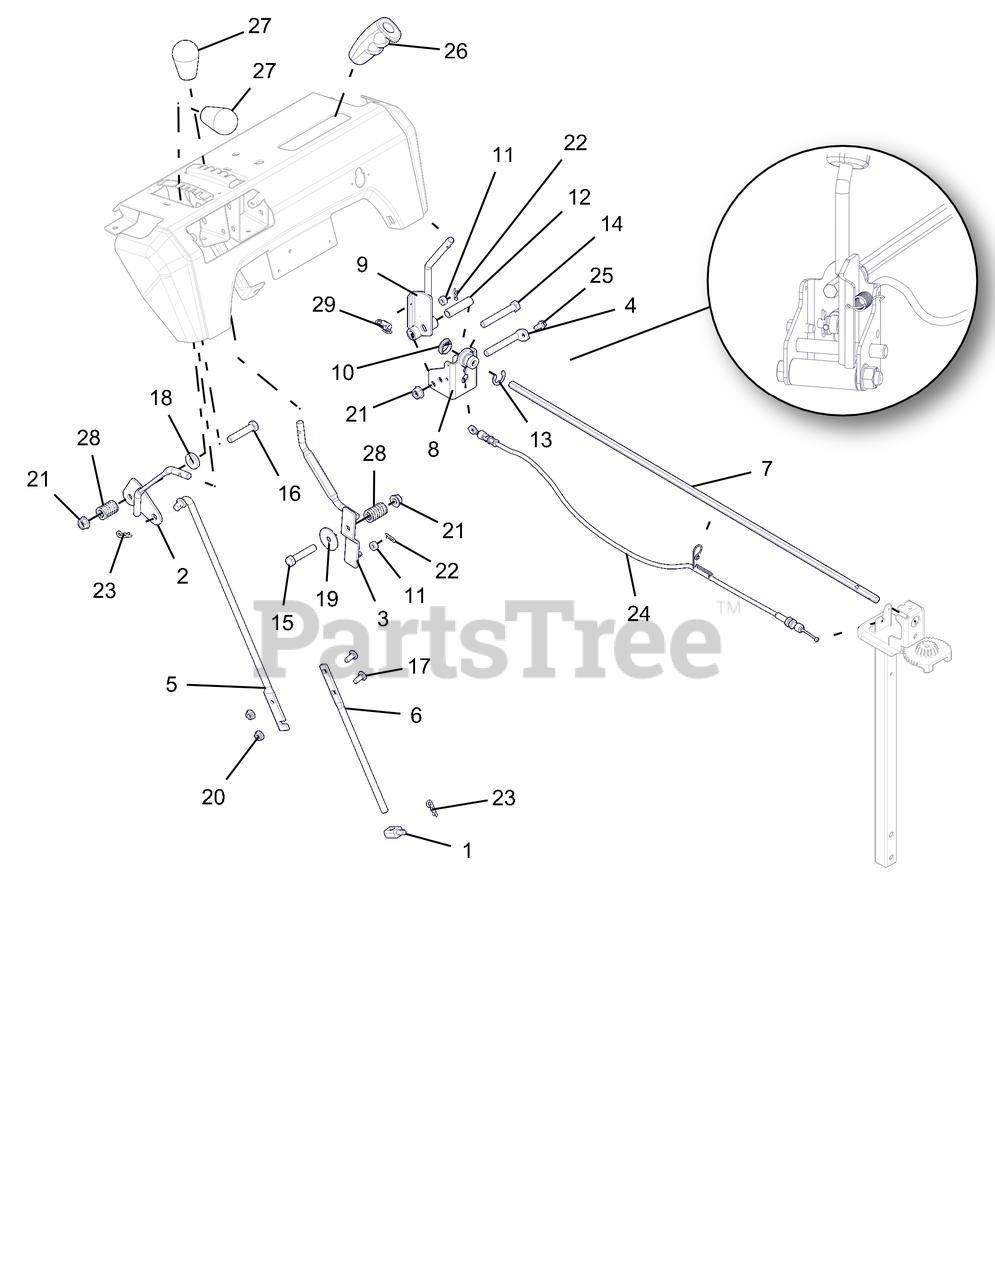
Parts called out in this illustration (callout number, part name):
1	PIVOT,SHIFT ROD .375-16(TRUNN)
2	WELDMENT, CONTROL LEVER(SHIFT)
3	WELDMENT, CONTROL LEVER (DEFL)
4	ROD, PIVOT - INTERLOCK
5	ROD, SHIFT - UPPER
6	ROD, SHIFT - LOWER
7	ROD, HEX - CHUTE ROTATION
8	WELDMENT-CONTROL BRACKET-CHUTE
9	WELDMENT, CONTROL LEVER
10	BUSHING, POLYLINER-.75 SNAPIN
11	BSHG-SLV .265X.500X.219
12	SPCR, WHEEL .385X.500X2.00
13	E-RING .750X.050
14	@BLT-HEX .38-16X2.75 GR5 YWZC
15	@BLT-HEX .38-16X2.00 GR5 YWZC
16	@BLT-HEX .31-18X2.25 GR5 YWZC
17	@BLT-RDHDSQNK .25-20X.75 G5YZ
18	WSHR-FL-STL .630X1.005X.062 YZ
19	WSHR-FL-STL .380X1.50X.062 YWZ
20	@NUT-LK-CTR-FLG .25-20 YWZC
21	@NUT-LK-TOP-FLG .38-16 YWZC
22	PIN-HAIR INT .06X.18X.77
23	PIN-HAIR INT .08X.18X1.18 YWZC
24	CABLE, CHUTE LOCK, PRO
25	SCR-TAP .25-20X.50 HWH TR YWZ
26	CONTROL HANDLE, QUICK TURN
27	KNOB,SOFT TEARDROP,PUSH-ON GRY
28	SG-COMP .125X.781X1.250
29	SPRING-EXT .047X.438X1.45
